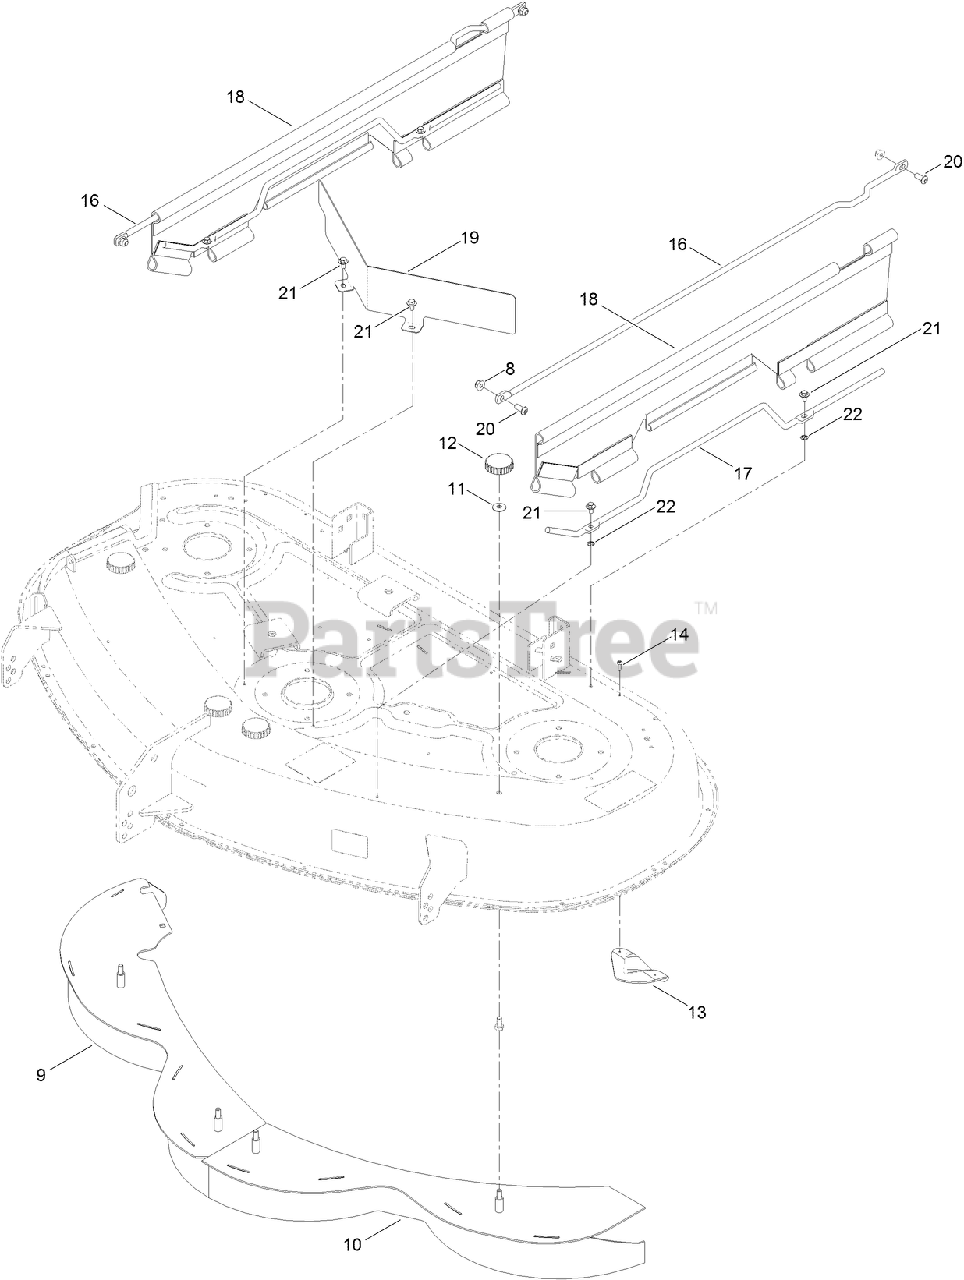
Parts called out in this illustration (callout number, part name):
8	NUT-HF, NI
9	RH BAFFLE ASM
10	LH BAFFLE ASM
11	WASHER-BELLEVILLE
13	PLATE-KICKER
14	SCREW-PPH
16	ROD-SUPPORT, UPPER
17	ROD SUPPORT, LOWER
18	GUARD-SIDE
19	SHIELD-FRONT
20	SCREW-HSBH
21	SCREW-HHFTF
22	NUT-RETAINING
